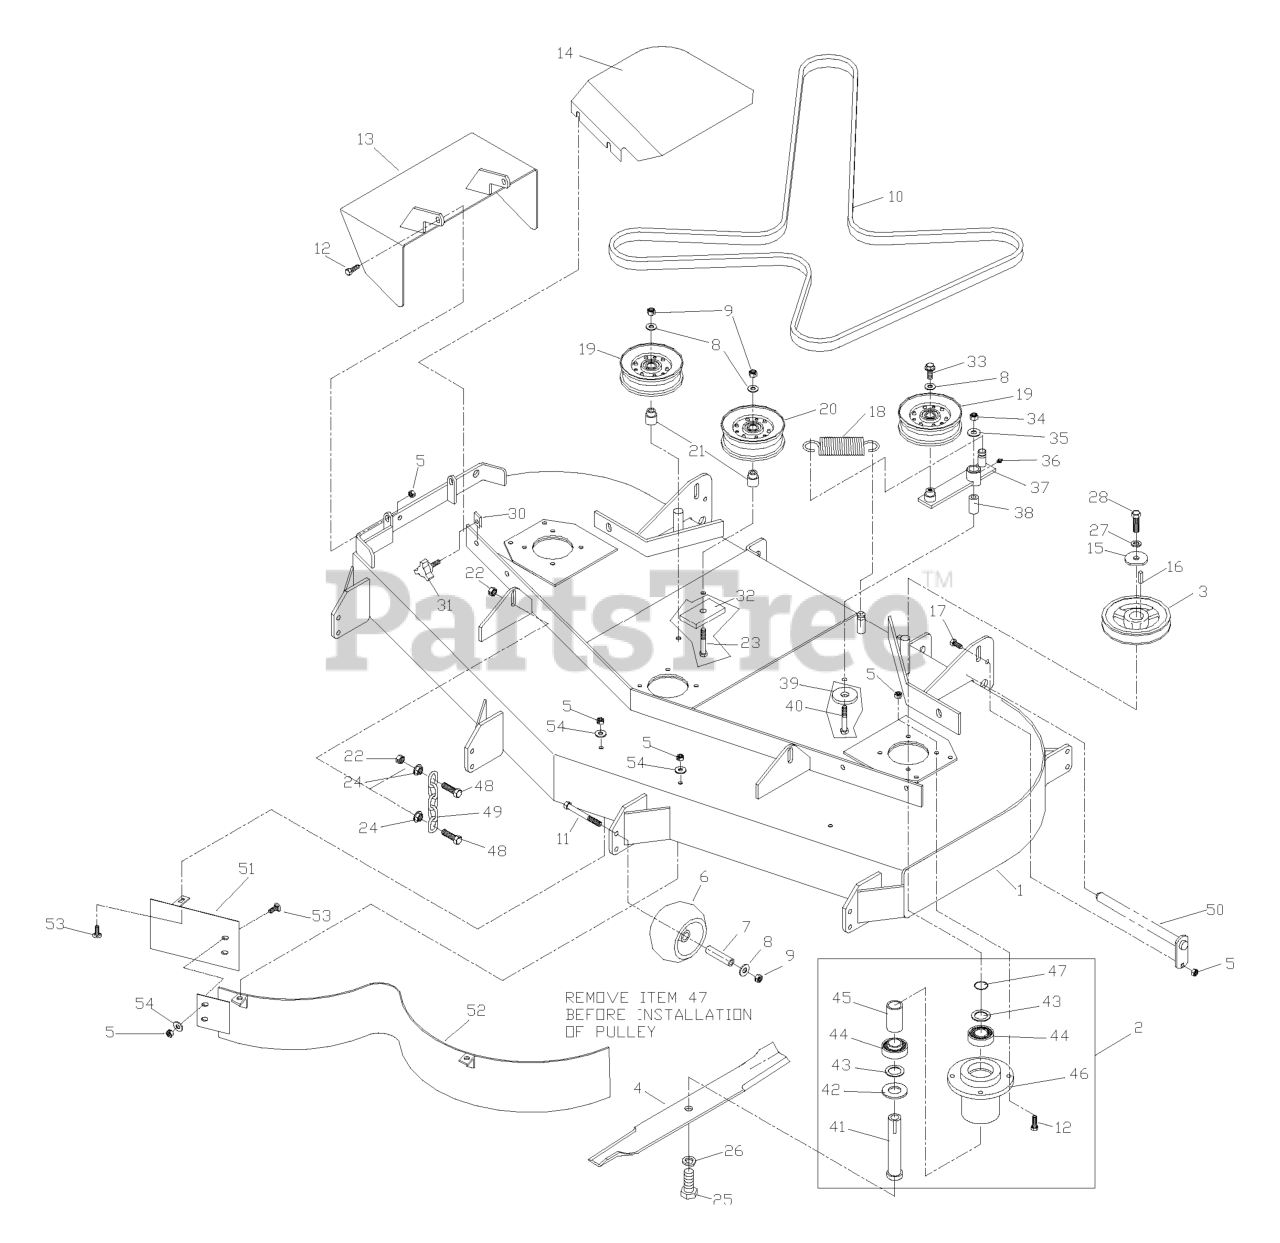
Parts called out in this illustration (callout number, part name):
1	DECK W/DECALS 61" HUS
1	DECK W/DECALS 52" HUS WSL
2	HOUSING ASM.
3	PULLEY 52" DECK
4	BLADE OEM 21" (61" DECK)
4	BLADE OEM 18"
5	NUT 5/16C CENTERLOCK
6	ANTI-SCALP ROLLER
8	WASHER 3/8 FLAT
9	NUT 3/8C CENTERBLOCK
10	DECK BELT 61
10	BELT, DECK
11	HCS 3/8C X 3 1/2
12	HCS 5/16C X 1
13	DISCHARGE CHUTE
14	61 B.S.PAINTED, RT
14	52 B.S.PAINTED,RT
15	SPINDLE WASHER
16	KEY 1/4 SQ X 1 1/8
17	HCS 5/16C X 3/4
18	DECK SPRING
19	IDLER PULLEY
20	IDLER PULLEY (TALL)
21	IDLER BUSHING
22	NUT 7/16C CENTERLOCK
23	HCS 3/8C X 2 1/2
24	NUT 7/16C WHIZ
25	HCS 5/8F X 1 1/4
26	LOCKWASHER 5/8
27	WASHER 7/16 LOCK
28	HCS 7/16F X 1 1/2
29	61 B.S.PAINTED, LT ORANGE
29	52 B.S.PAINTED, LT
30	U-CLIP 5/16-18 NUT RETAINER
31	KNOB W/STUD
32	SUPPORT PLATE
33	4CS 3/8C X 1 SERRATED HEAD
34	NUT 1/2-13 HEX NYLOC ZD
35	WASHER 1/2 FLAT
36	ZERK
38	PIVOT BUSHING
39	WASHER, SUPPORT
40	HCS 1/2C X 3 1/4
42	MACHINERY BUSHING 10 GA.
43	BUSHING.MACHINE.18.GAUGE
44	BEARING
46	HOUSING, DIE CAST
48	HCS 7/16C X 1 1/2
49	LIFT CHAIN
51	CENTER BAFFLE - 52"
51	CENTER BAFFLE - 61
52	MAIN BAFFLE 52"
52	MAIN BAFFLE - 61" BLK
53	CARRIAGE BOLT 5/16C X 5/8"
54	WASHER 5/16 FLAT
